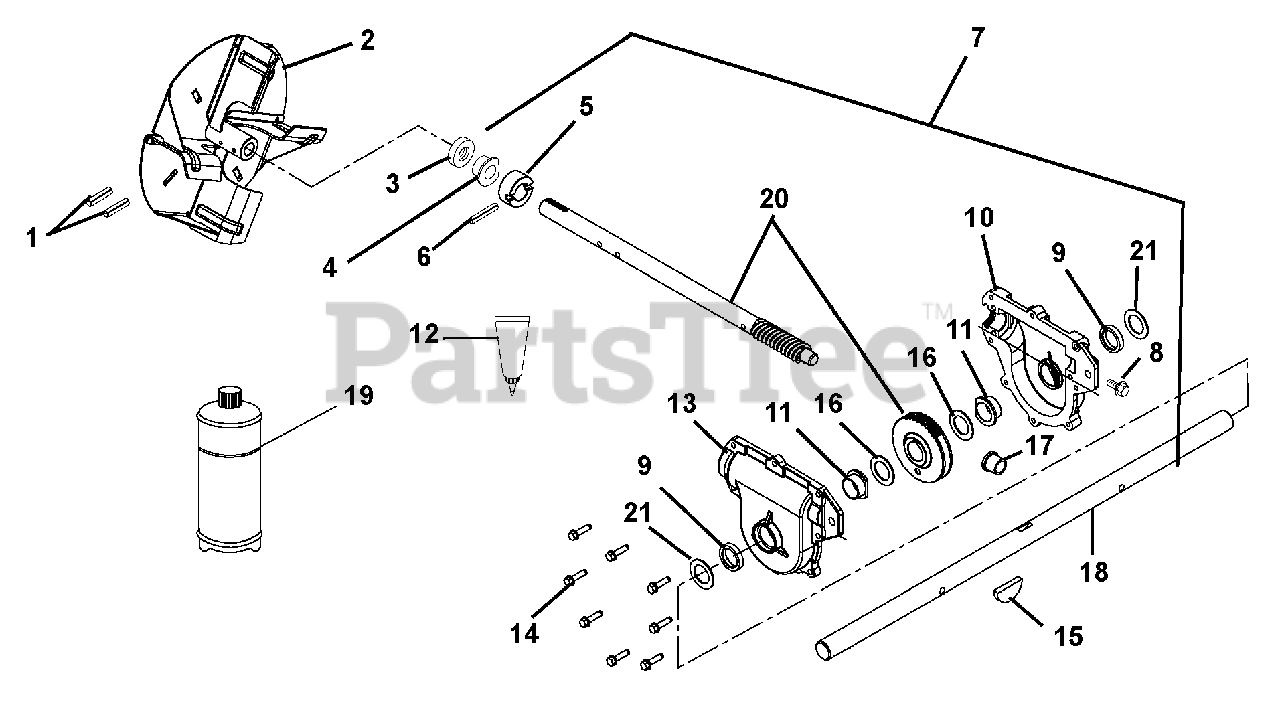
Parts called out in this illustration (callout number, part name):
1	PIN-ROLL .250X1.75
2	IMPELLER-14" 4 BLADE
3	SEAL-OIL .875X1.375X.25 RBR OD
4	BSHG-FLG .876 X 1.500 X .750
5	THRUST COLLAR, .875" ID
6	PIN-GRV .250X1.50 TP E
7	GEARCASE ASS'Y - 26" ALUMINUM
7	GEAR CASE, ALUM-LARGE 28"
7	GEAR CASE, ALUM-LARGE 32"
8	SCR-TAP .38-16X.75 ROLOK YZ WX
9	SEAL-OIL 1.000X1.375X.250
10	GEARCASE, ALUMINUM, LH
11	BSHG-FLG 1.003X1.5X.625
12	LOCTITE 518 GASKET--6ML TUBE
13	GEARCASE, ALUMINUM, RH
14	@SCR-TAP .25-20X1.00 HWH TR YZ
15	KEY-WDRF .25X.875X.375 SAE A
16	WSHR-HRD-THRS 1.007X1.542X.062
17	BSHG-FLG .629 X 1.000 X .750
18	SHAFT, RAKE-26"
18	SHAFT, RAKE-28"
18	SHAFT, RAKE-32"
19	ARIENS 16 OZ.BOTTLE OF L2 LUBE
20	ASSY, WORM SHAFT & GEAR
21	WSHR-FL-STL 1.010X1.505X.062YZ
